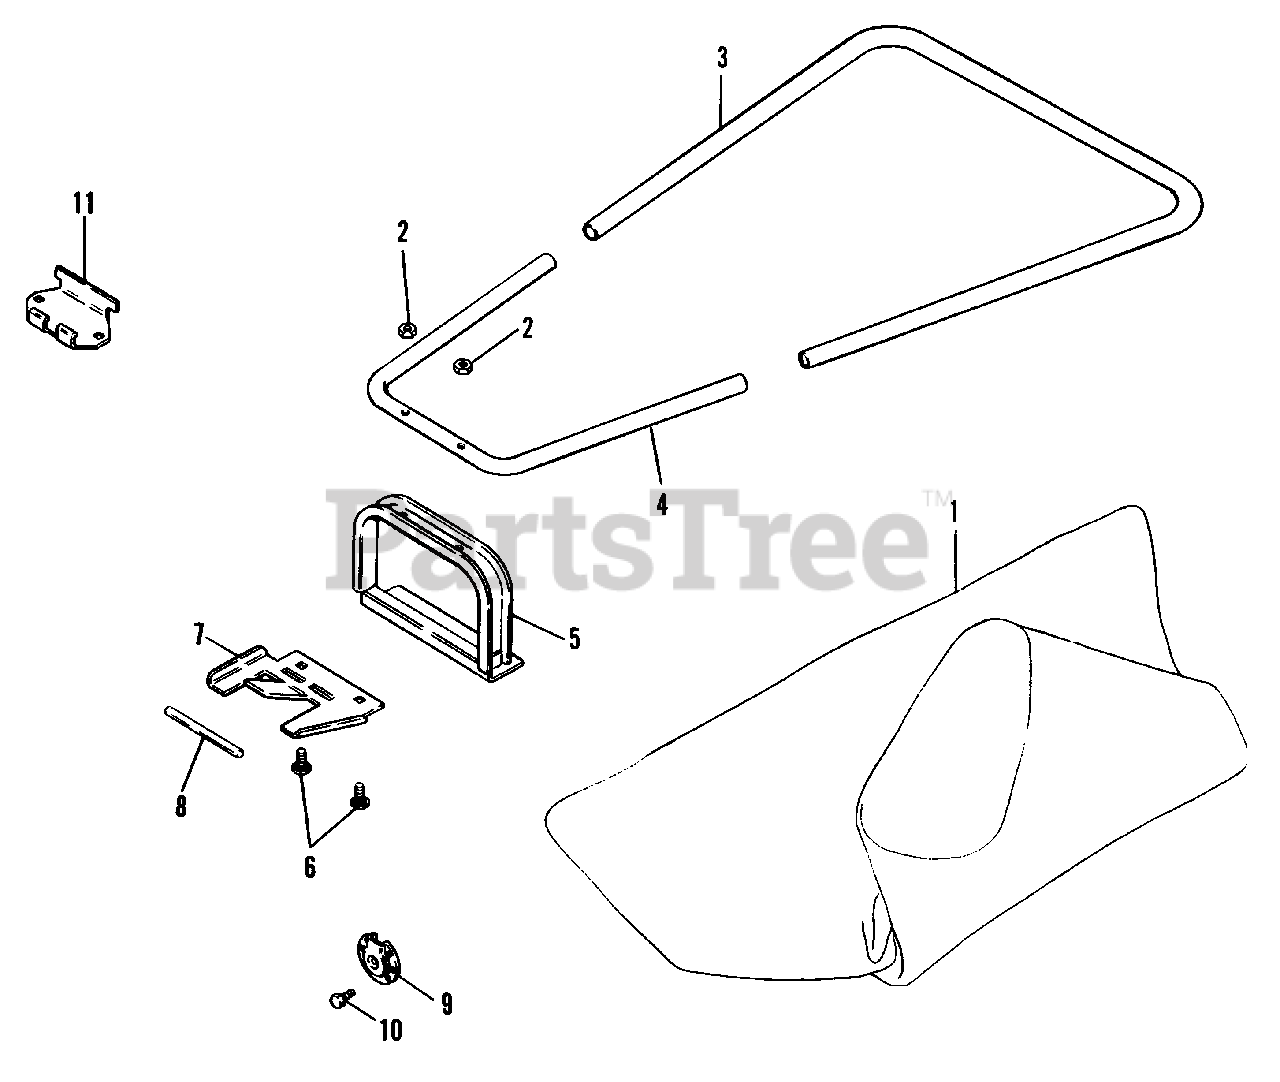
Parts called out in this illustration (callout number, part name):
1	GRASS BAG
2	KEPNUT, 1/4-20
3	SUPPORT TUBE, Upper
4	LOWER FRAME SUPPORT
5	FRAME ASSY.
6	CARRIAGE BOLT, 1/4-20 x 3/4
7	DECK BRACKET
8	SUPPORT PIN
9	MUFFLER DEFLECTOR
10	SCREW, Hex Hd., 8-32 x 5/8
11	DECK BRACKET (Supplied With Certain Units)
